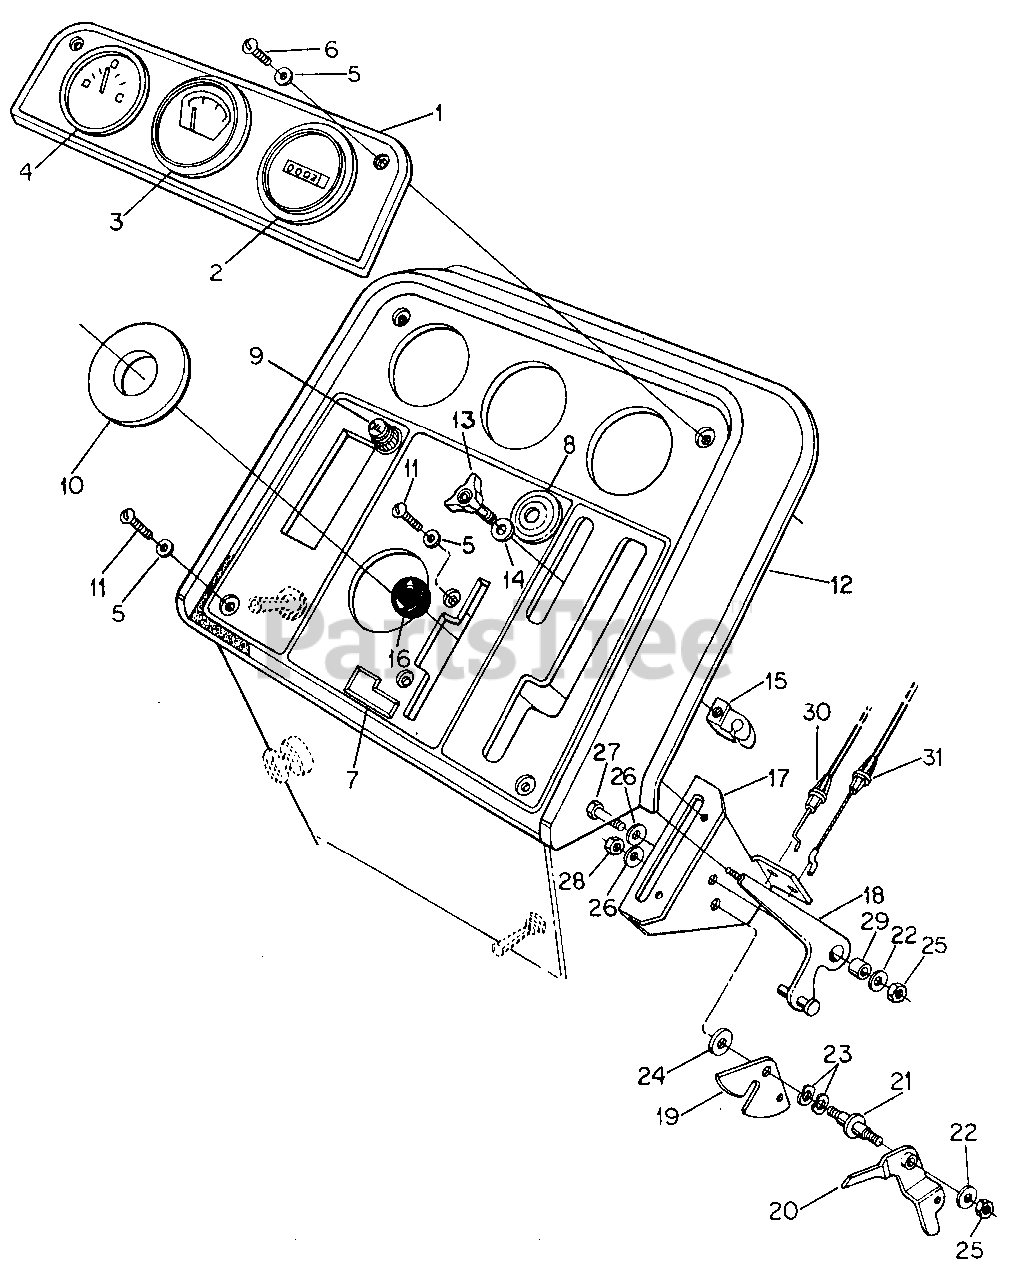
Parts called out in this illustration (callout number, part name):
1	Cover, Panel
2	Package, Hourmeter
3	Gauge, Water Temperature
4	Indicator, Charge
5	Washer, Flat
6	Screw, Tap
7	Plate, Throttle
8	Indicator, Glow Plug
9	Light, Oil Indicator
10	Grommet, Instrument Panel
11	Screw, Tapping
12	Panel, Instrument
14	Washer, .266 X .625 X .036
15	Stop, Handle Detent
16	Knob, Ball
17	Support, Throttle Control
18	Lever, Throttle Control
19	Cam, Throttle Control
20	Cam, Fuel Shut-Off
21	Shaft, Pivot
22	Washer, Ft R/Hole 11/32 X 5/8 X 16 Ga
23	Washer, Spring
24	Disc, Friction
25	Nut, 5/16 Cad P/T Lock Type 5
26	Washer, Bell
27	Bolt, 5/16 X 1 Type 5
28	Nut, 5/16 Type 5
30	Cable, Throttle
31	Cable, Shut-Off
